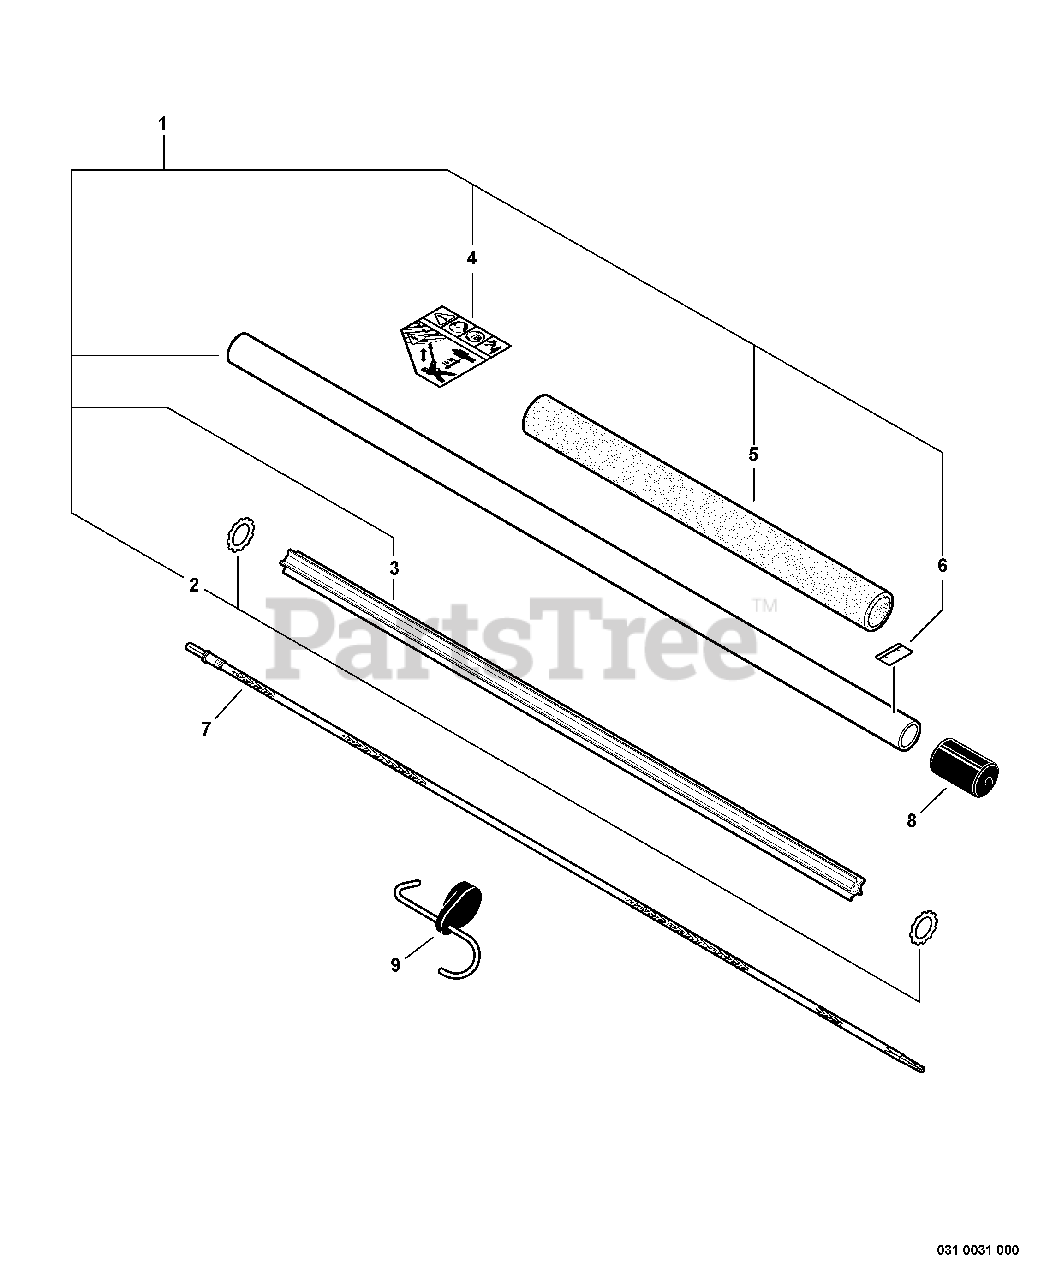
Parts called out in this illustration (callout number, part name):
1	PIPE, MAIN
3	LINER - FLEXIBLE
4	LABEL, CAUTION
5	GRIP, HANDLE
6	LABEL - ALIGNMENT
7	DRIVESHAFT - FLEXIBLE
8	CAP, MAIN PIPE
9	HANGER, ATTACHMENT
